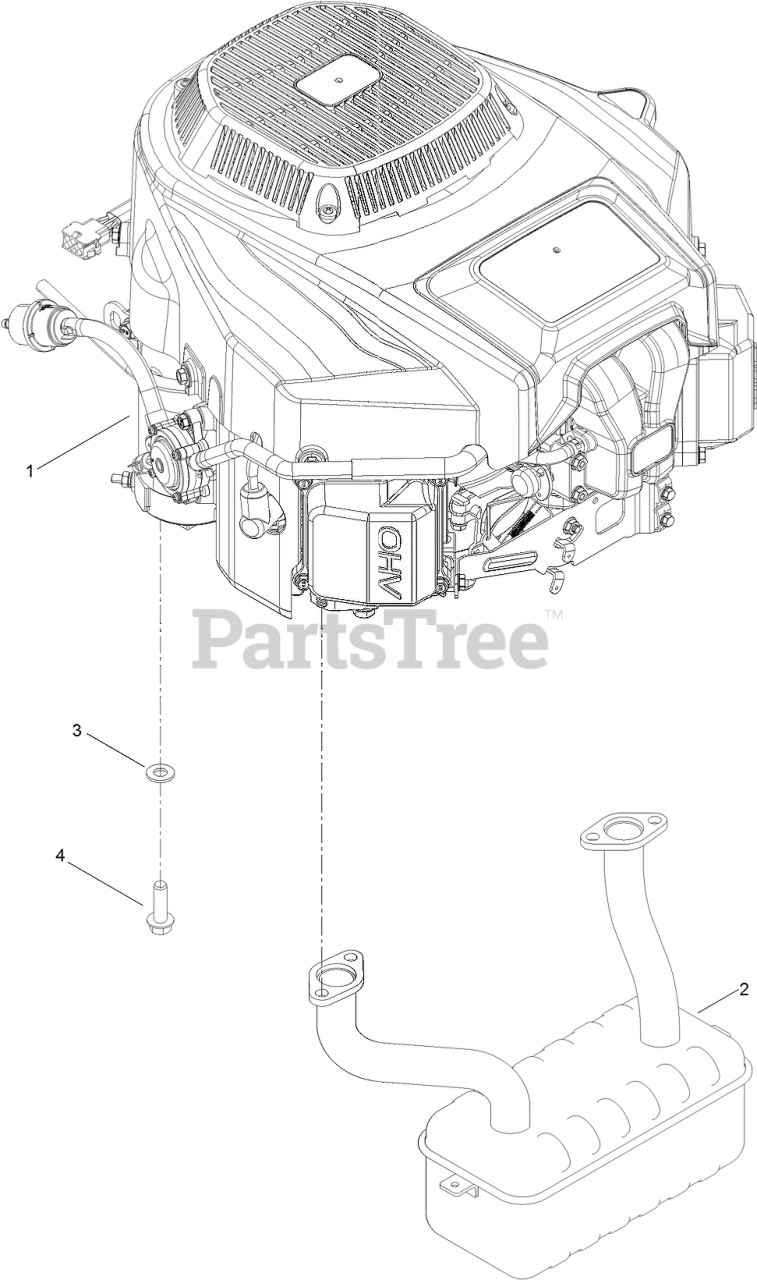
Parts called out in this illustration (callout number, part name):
1	ENGINE-2P77F
2	MUFFLER
3	WASHER-FLAT
4	SCREW-HWH, THD ROLL
